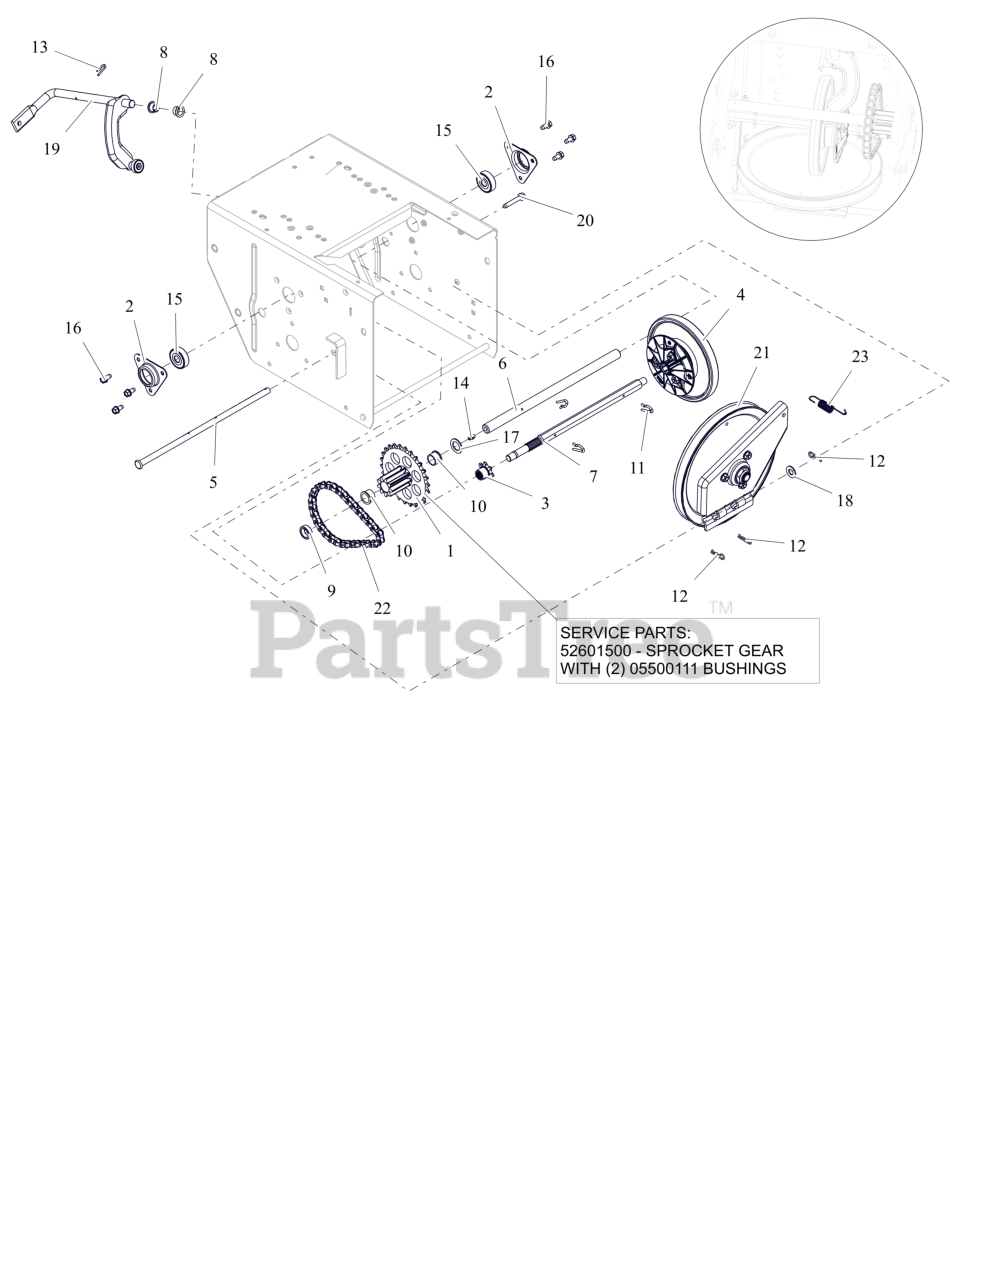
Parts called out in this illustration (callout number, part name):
1	PINION & SPROCKET
1	PINION & SPROCKET W/BUSHINGS
2	FLANGE, BEARING
3	SPROCKET, PINION 7T W/SPLINE
4	DISC, FRICTION DRIVE-ASSEMBLY
5	PIN, PIVOT
6	SHAFT, PINION
7	SHAFT, HEX
8	BUSHING, POLYLINER-.50 SPLIT
9	BSHG-SLV, .635X.880X.305
10	BSHG-FLG .625X.750X.500X.875
11	PIN, SPRING CLIP
12	PIN, HAIR #213 .08X1.19 ZCC
13	CLIP, SPRING
14	ZERK,FITTING .25X.125 DRIVE IN
15	BRG-BALL .437X1.375X.437
16	SCR-TAP .25-20X.50 HWH ZCC
17	WSHR, FLT .630X1.005X.062 ZCC
18	WSHR,FLT .406X.812X.065 ZCC
19	ARM, SHIFT - ASSEMBLY
20	SCR,TAP .25-20X1.50 HWH TR ZCC
21	PLATE, SWING ASSEMBLY-DEEP
22	CHAIN - #41, 32 PITCHES
23	SG-TENS .048X.50X2.8
